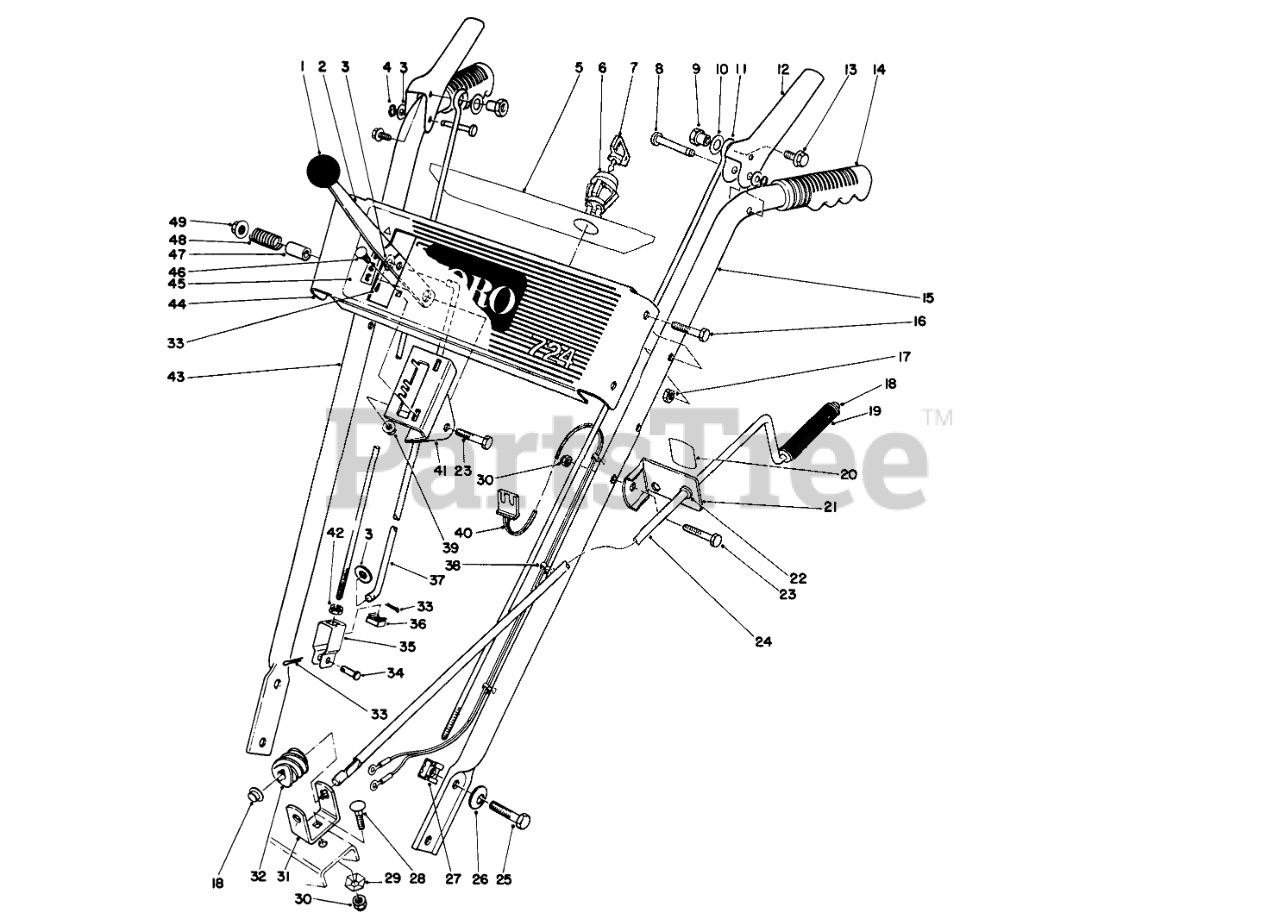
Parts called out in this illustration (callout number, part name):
2	Selector-Speed
3	WASHER-PLAIN
4	RING-CLIP
5	DECAL - ESCUTCHEON BACK
6	SWITCH
7	KEY-IGNITION
8	PIN-LEVER, CONTROL
9	POST-MOUNTING, LINKAGE
10	WASHER-FLAT
11	LINK-UPPER
12	HANDLE-CONTROL
13	SCREW-HHF
14	GRIP-HANDLE
15	Handle-Left
16	SCREW-HH
17	NUT-LOCK, NI
18	RETAINER-PUSH ON
19	Grip-Rod
20	DECAL-CHUTE DIRECTION
21	Bracket-Chute Control (Incl. ref. #20 & 22)
22	Bushing
23	SCREW-HH
24	ROD-CONTROL, CHUTE
25	SCREW-HH
26	WASHER-BELLEVILLE
28	SCREW-CARR
29	WASHER-LOCK
30	NUT-LOCK, NI
31	BRACKET-WORM
32	GEAR-WORM, CHUTE
33	PIN-COTTER
34	PIN-CLEVIS
35	CLEVIS
36	NUT-RETAINED
37	ROD-SELECTOR, SPEED
38	Mount-Wire
39	NUT-HF
40	WIRE HARNESS
41	Mount-Speed Selector
42	NUT-JAM
43	Handle-Right
44	ESCUTCHEON PLT B
45	DECAL - ESCUTCHEON
46	SCREW-CARR
47	SPACER
48	SPRING
49	NUT-HF
50	WASHER-FLAT
